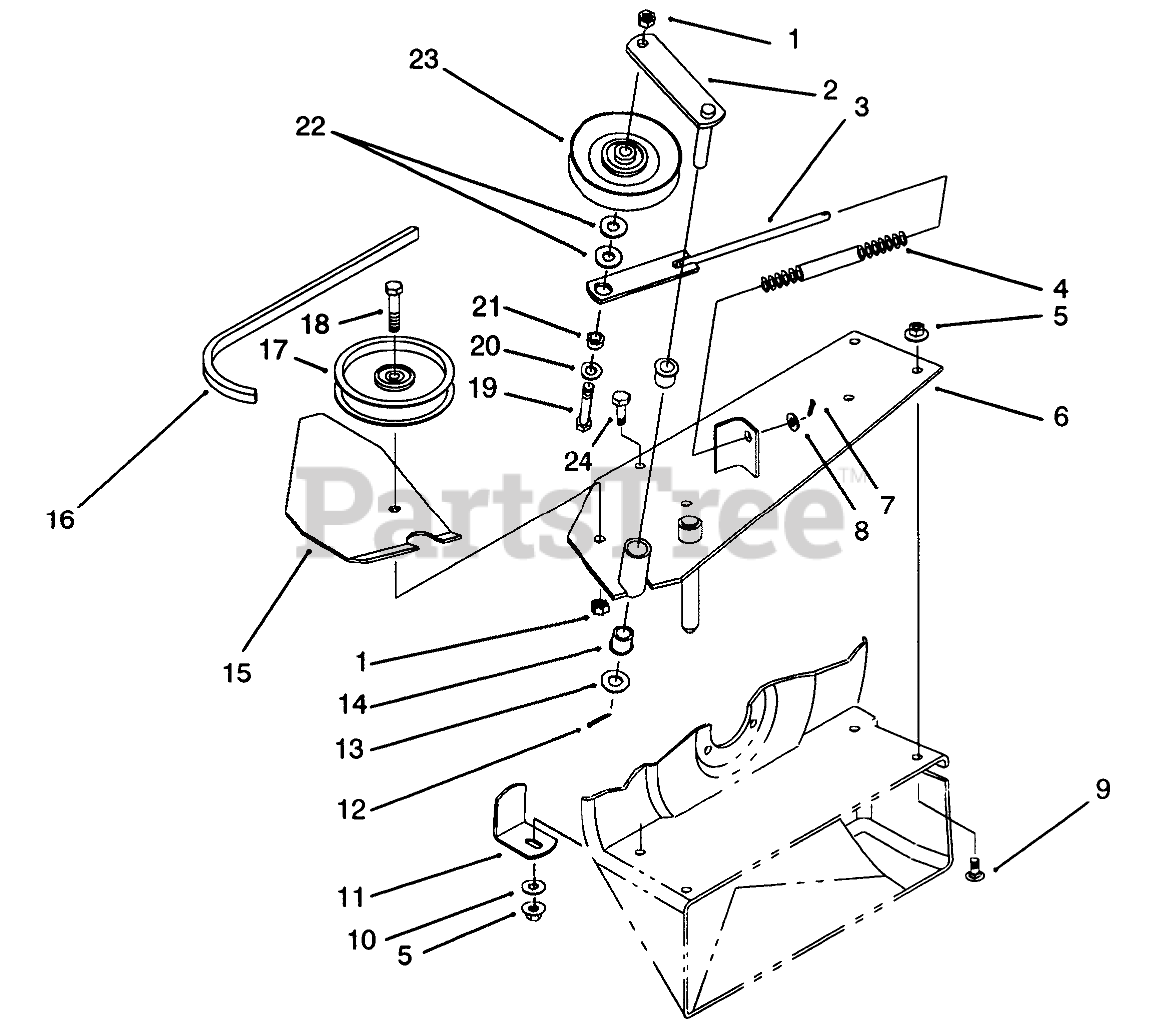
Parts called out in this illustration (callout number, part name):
1	NUT-LOCK, NI
2	IDLER ARM ASM
3	SPRING-ROD
4	SPRING-COMPRESSION
5	NUT-HF
6	BLOWER-MTG ASM
7	PIN-COTTER
8	WASHER-PLAIN
9	BOLT-CARR
10	WASHER-FLAT
11	BRACKET-SUPPORT, HOUSING
12	PIN-COTTER
13	WASHER-FLAT
14	BUSHING
15	SHIELD SUPPORT B
16	V-BELT
17	Pulley
18	SCREW-HH
19	SCREW-HH
20	WASHER-FLAT
21	SPACER
22	WASHER-FLAT
23	"V" Pulley
24	SCREW-HH
